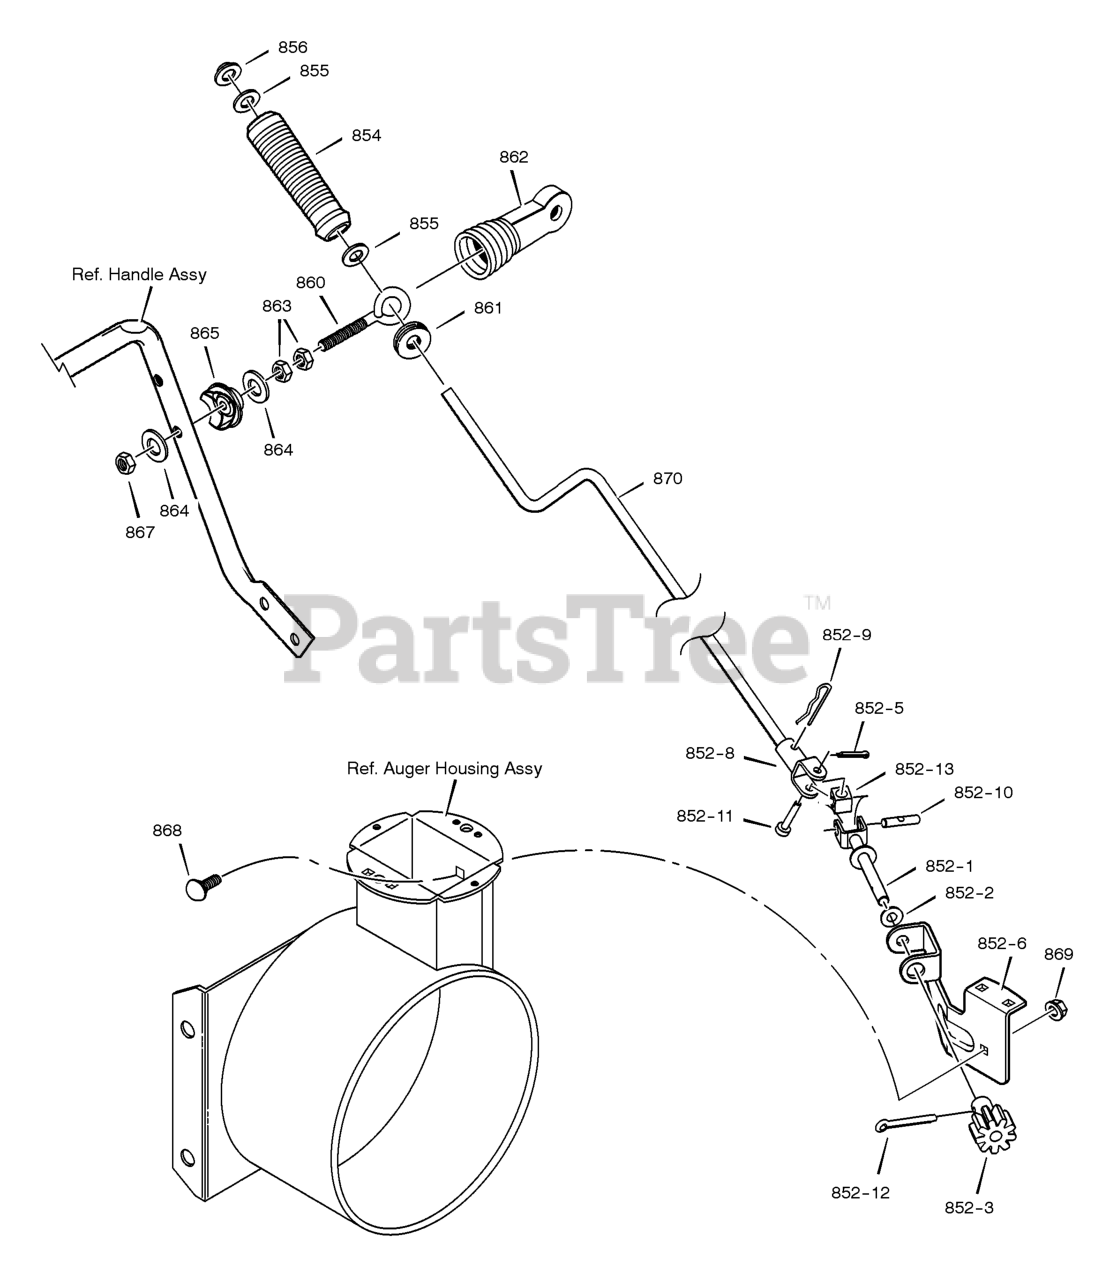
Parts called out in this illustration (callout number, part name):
852-1	ASSEMBLY, YOKE & ROD
852-2	WASHER, CURVED SPRING
852-3	GEAR, CHUTE ROTATION 9T
852-5	PIN, COTTER
852-6	BRACKET, GEAR MOUNT
852-7	PIN, COTTER
852-8	ASSEMBLY, YOKE ADAPTER YZ
852-9	PIN, HAIR
852-10	PIN, UNIVERSAL JOINT
852-11	PIN, CLEVIS
852-12	PIN, COTTER
852-13	HOUSING, UNIVERSAL
854	KNOB, SLEEVE
855	FLATWASHER
856	NUT, PUSH ON 3/8"
860	EYE BOLT 3/8-16X6.00
861	GROMMET, EYE BOLT
862	BOOT, EYE BOLT
863	NUT, 3/8-16 HEXJAM
864	FLATWASHER .406X.81X.066
865	ADAPTER, BOOT
866	WASHER, FLAT
867	NUT, 3/8-16 HEXNYL
868	BOLT, CARRIAGE 1/4-20 X 1.00
869	NUT, 1/4-20
870	CRANK, ASSY CHUTE
